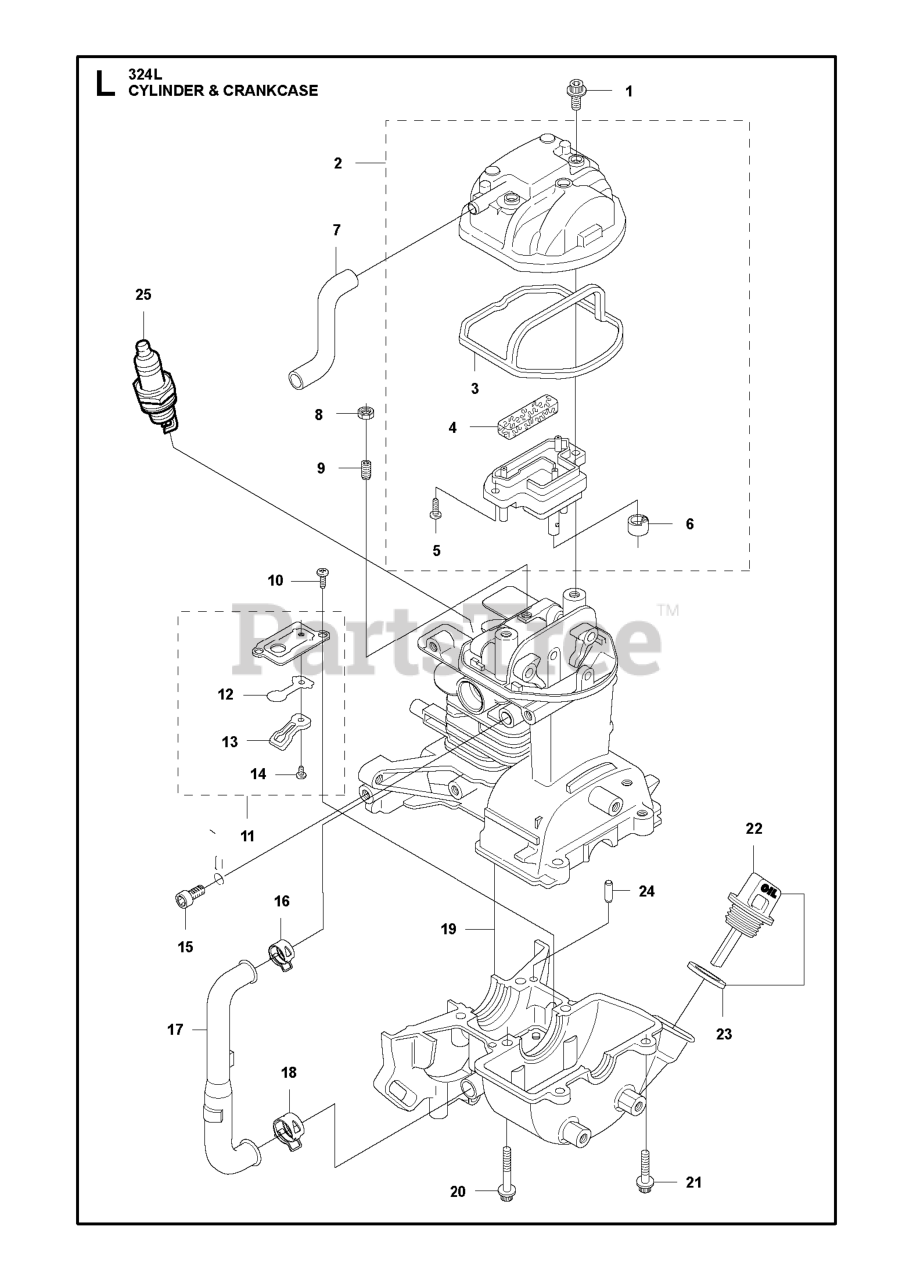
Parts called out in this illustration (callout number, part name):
13	MOVEMENT LIMITER
15	SCREW MC6S 5X10
19	CRANKCASE / CYLINDER
25	CMR5H NGK SPARK PLUG
25	SPARK PLUG
25	CMR6H NGK SPARK PLUG
